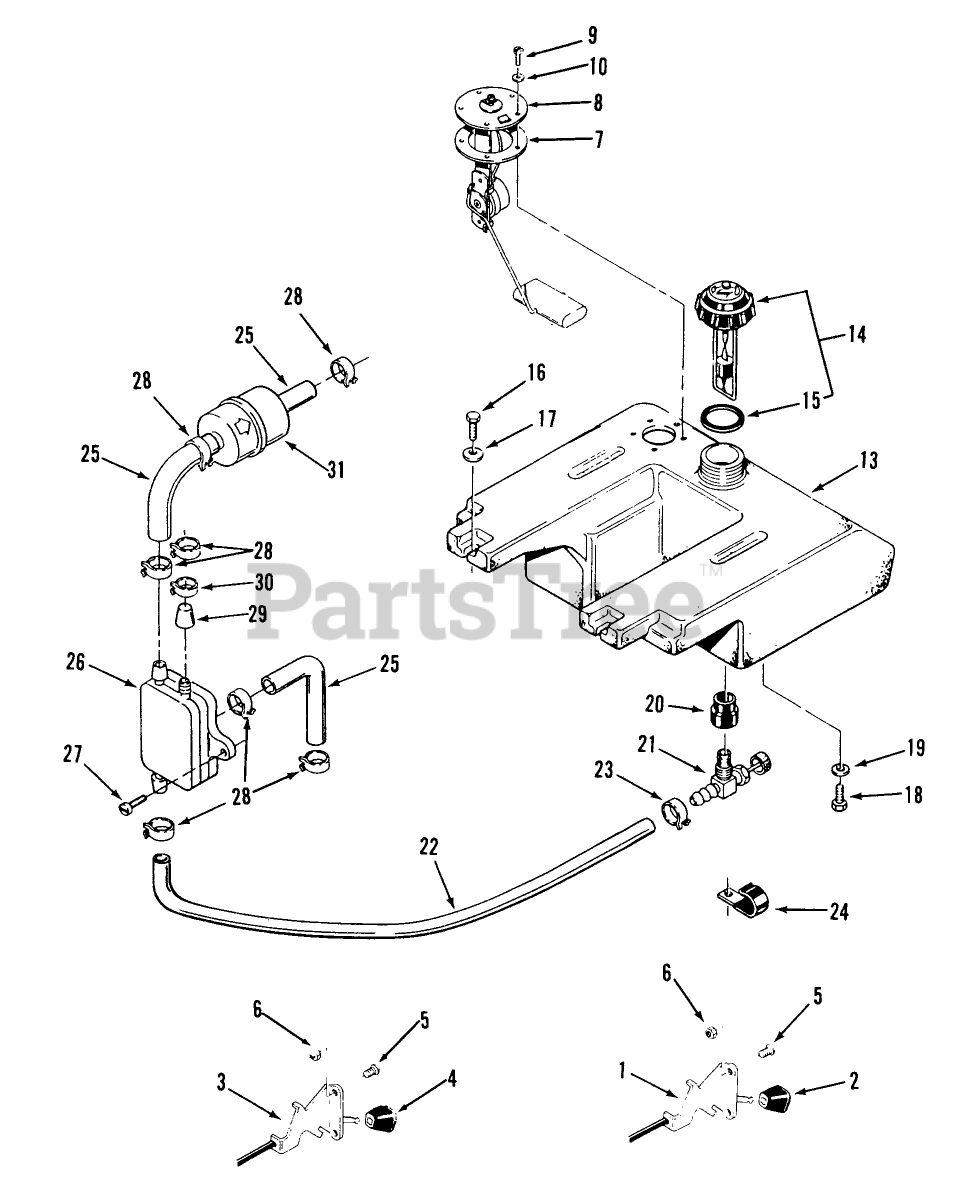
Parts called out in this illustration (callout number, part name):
1	CONTROL-THROTTLE
3	CONTROL-CHOKE
5	SCREW-PPH
7	GASKET-SENDER, FUEL
14	ASS'Y-GAS CAP
21	VALVE-FUEL
